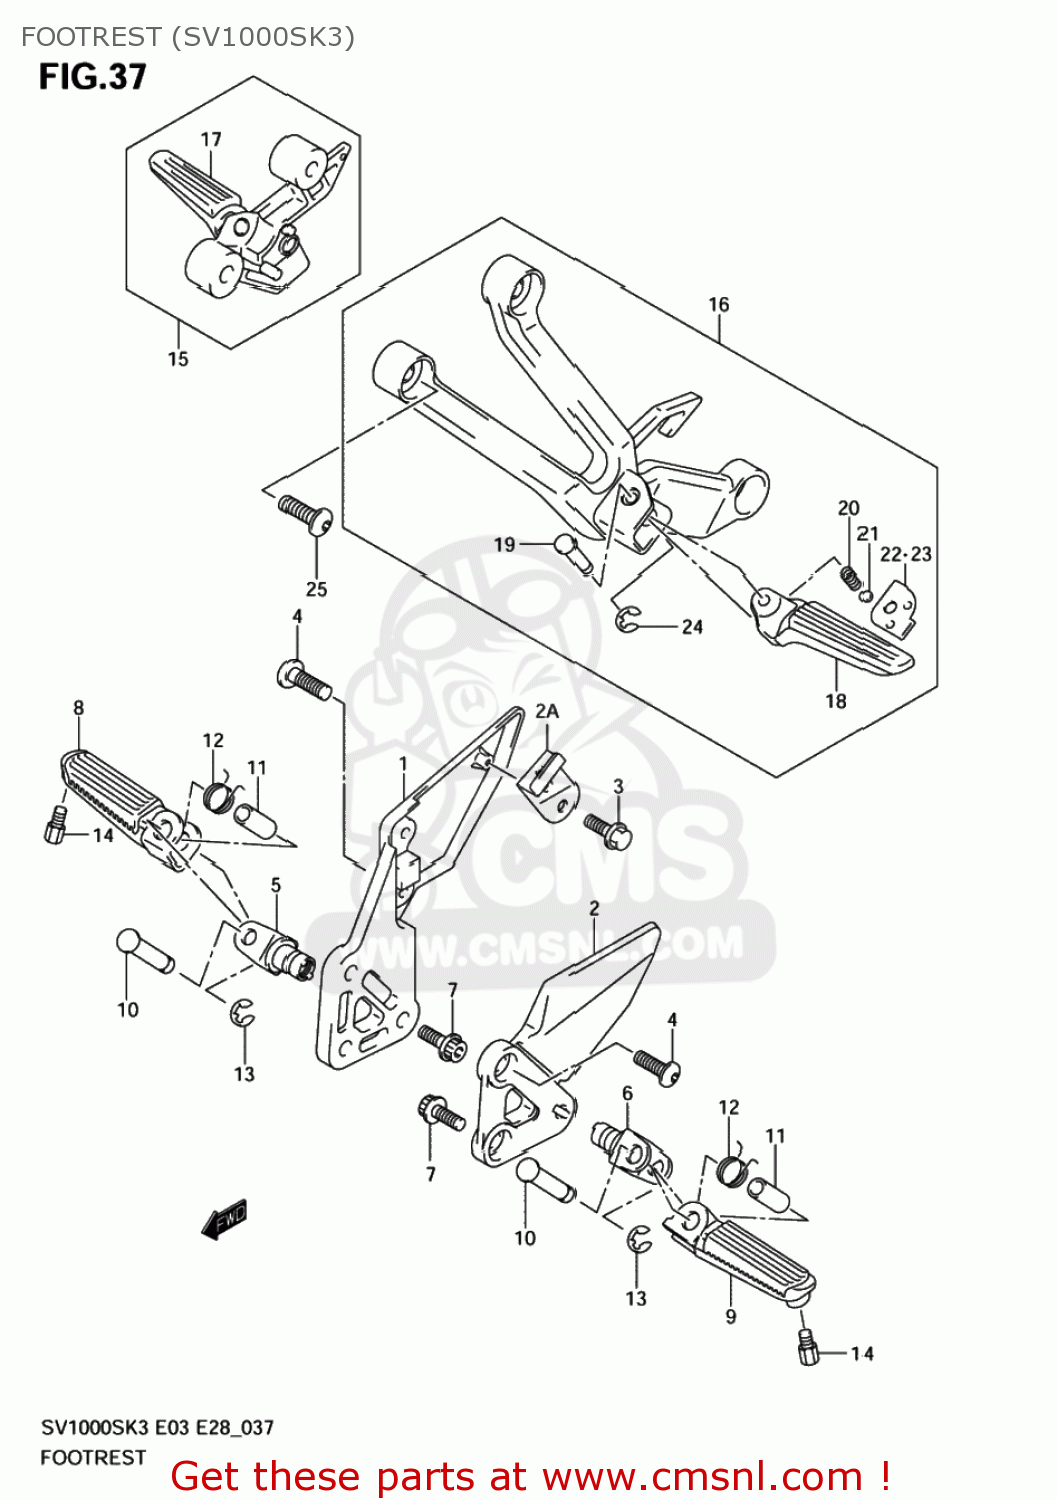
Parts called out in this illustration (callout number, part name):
1	BRACKET,FR FOOTREST,R
2	BRACKET,FR FOOTREST,L
2A	REINF,FOOTREST BRACKET
3	BOLT
4	BOLT 8X20
5	HOLDER,FOOTREST,R
6	HOLDER,FOOTREST,L
7	BOLT(10X28)
8	BAR,FR FOOTREST,R
9	BAR,FR FOOTREST,L
10	PIN
11	SPACER(8.1X12X22)
12	SPRING
13	E.RING
14	BOLT,BANK SENSOR
15	FOOTREST ASSY,PILLION,R
16	FOOTREST ASSY,PILLION,L
17	BAR,PILLION FOOTREST,R
18	BAR,PILLION FOOTREST,L
19	PIN
20	SPRING
21	BALL
22	PLATE,PILLION FOOT,R
23	PLATE,PILLION FOOT,L
24	E-RING
25	BOLT(8X23)
